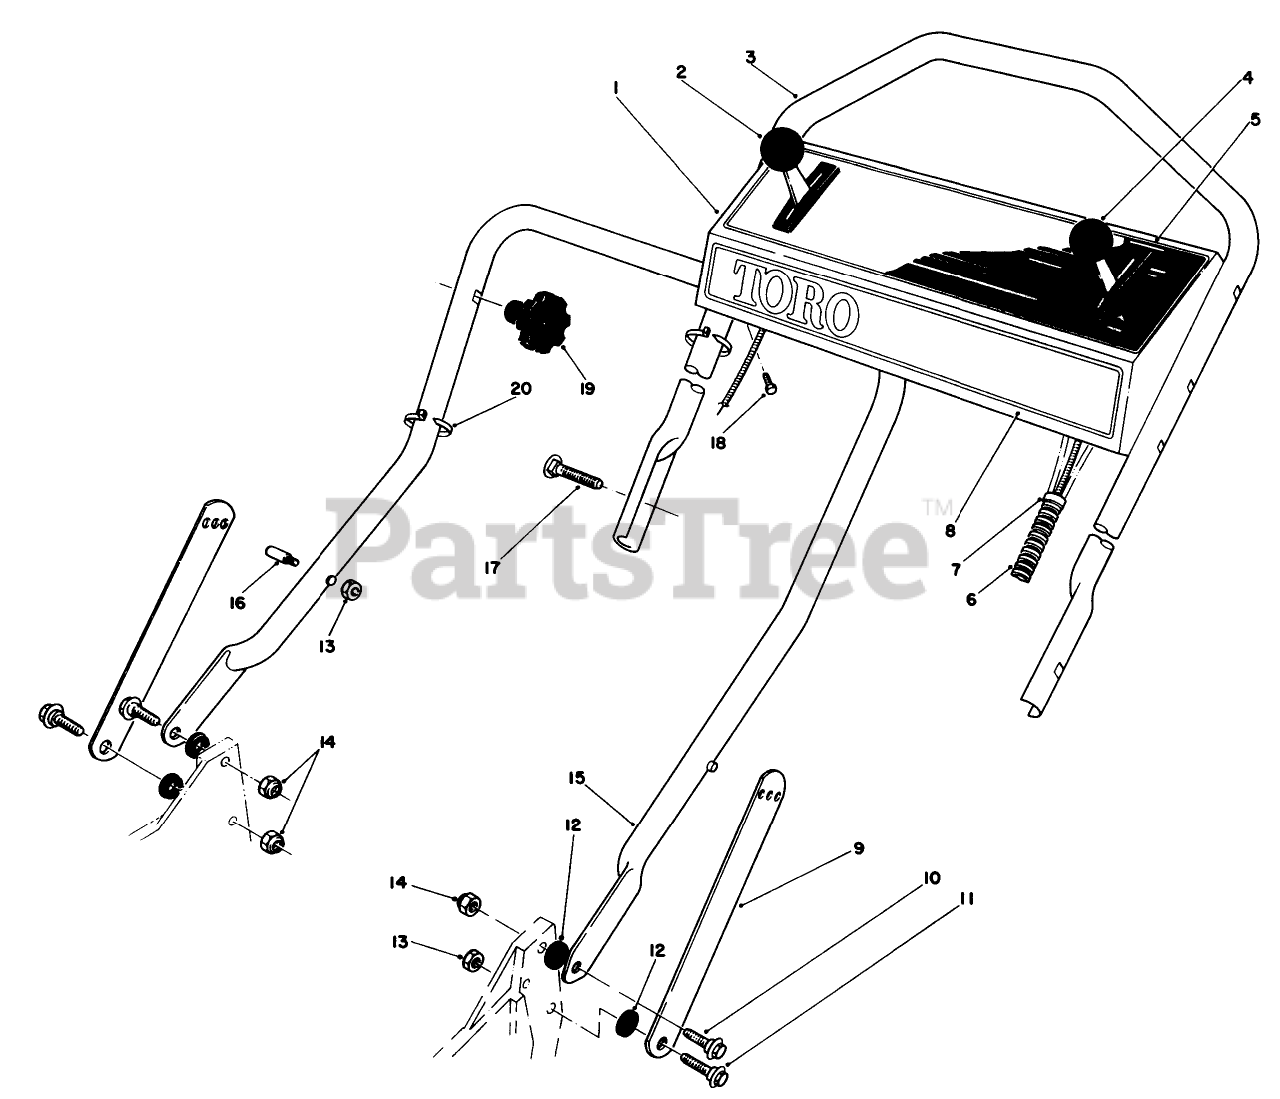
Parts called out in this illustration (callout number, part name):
2	GROUND SPEED CONTROL
4	SERVICE THROTTLE CONTRO
7	FITTING-RING
10	SCREW-SHOULDER
11	SCREW-SHOULDER
12	SPACER
13	NUT-LOCK, NI
14	NUT-LOCK, NI
16	HANDLE PIN
18	SCREW-HWHTF
20	TIE-CABLE
